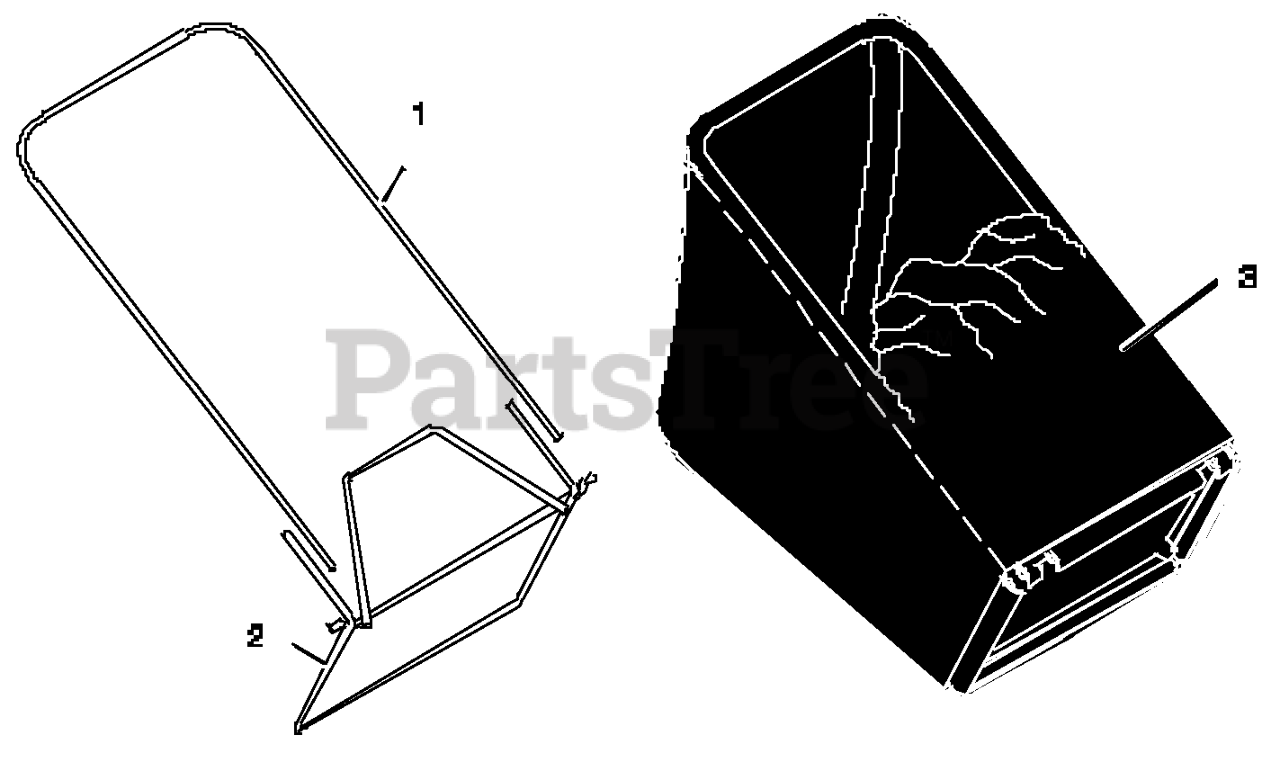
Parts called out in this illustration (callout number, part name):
1	Frame, Top
2	Frame Assembly
3	Bag, Cloth
